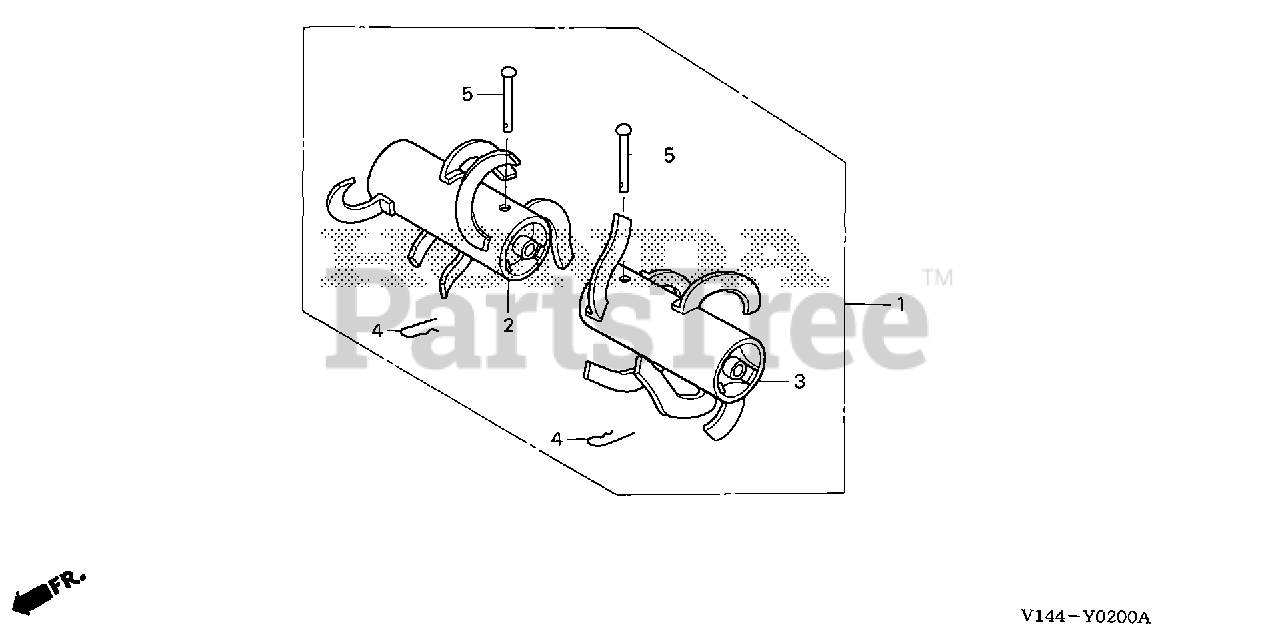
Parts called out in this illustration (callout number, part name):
1	ROTOR KIT, DRUM (N/A: SEE COMPONENTS)
2	ROTOR, R. DRUM
3	ROTOR, L. DRUM
4	PIN, SNAP (7MM)
5	PIN, DRUM ROTOR (8X100)
